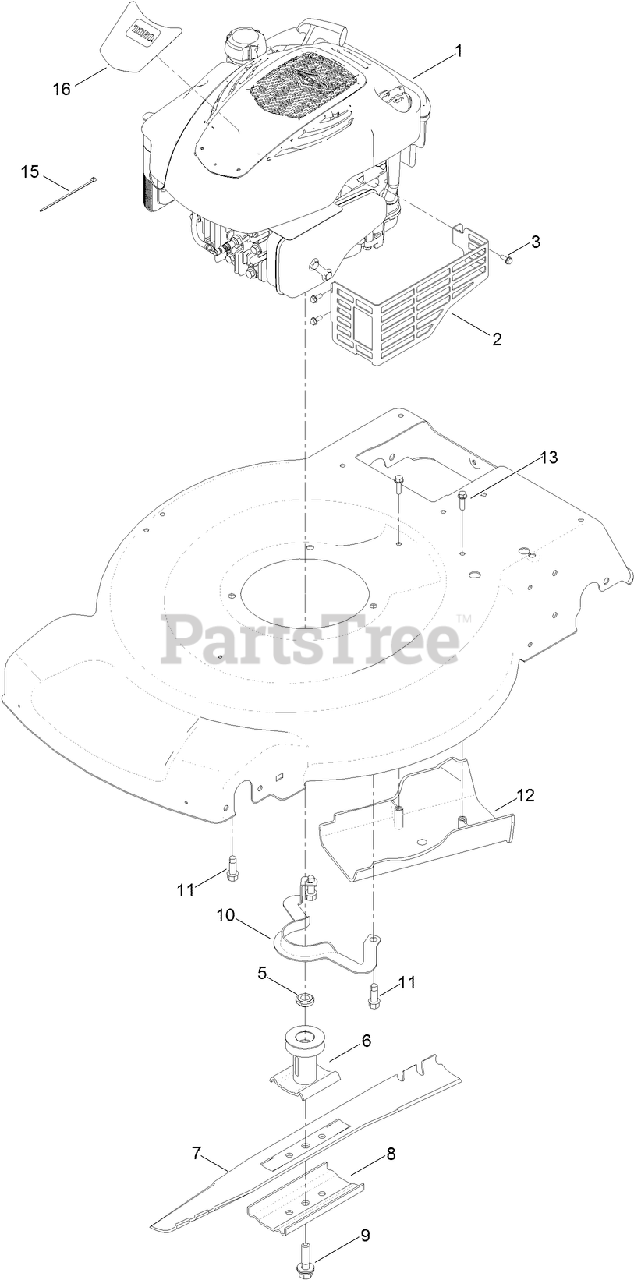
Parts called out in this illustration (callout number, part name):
2	SHIELD-MUFFLER
3	SCREW-TAPTITE
5	SPACER-DRIVER
6	DRIVER-BLADE
8	ACCELERATOR-BLADE
9	BOLT-BLADE
10	GUIDE-BELT
11	SCREW-TAPTITE
12	COVER-BELT
13	SCREW-HWH
15	TIE-CABLE, MOTOR
16	DECAL-SHROUD
